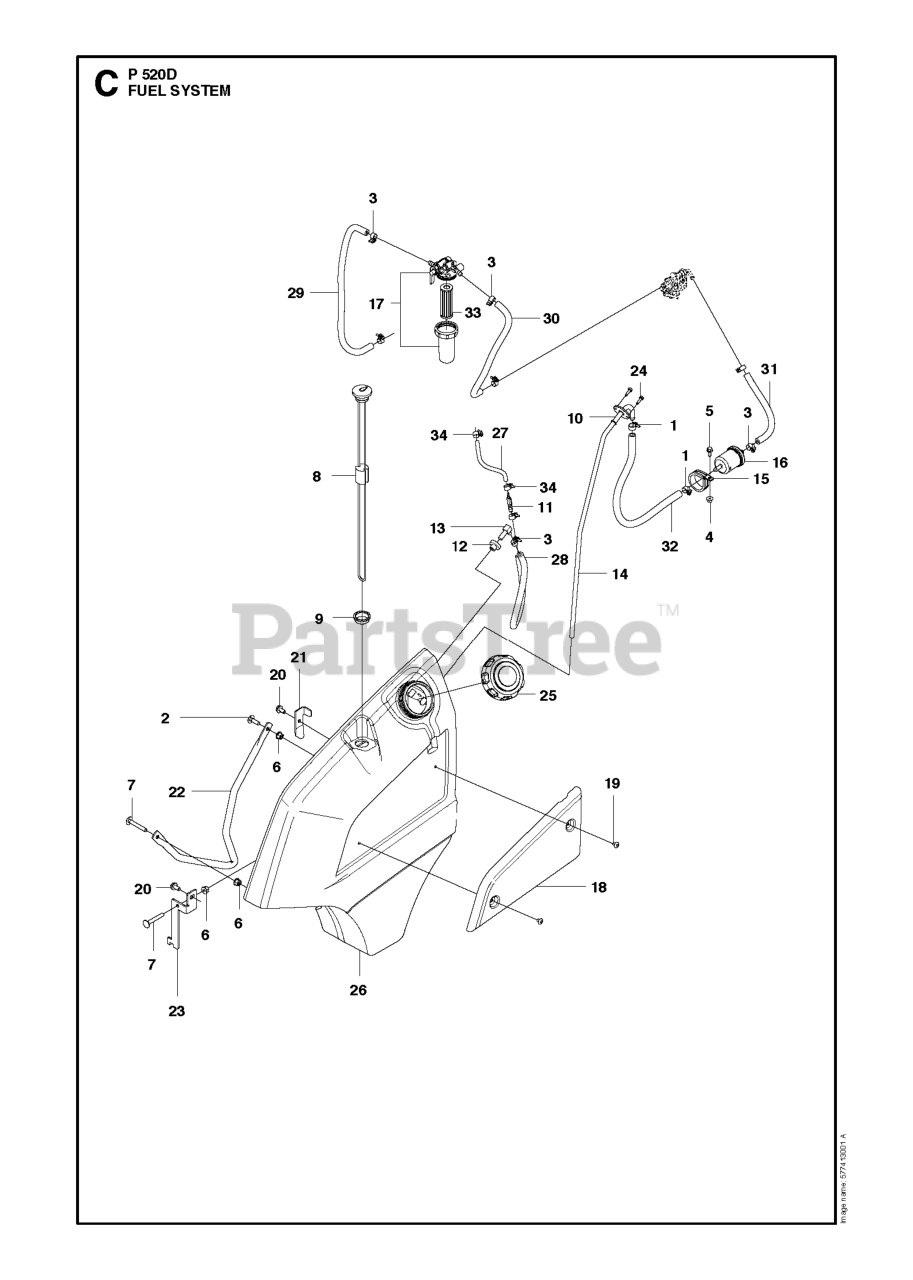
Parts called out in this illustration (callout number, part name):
1	HOSE CLAMP FUEL HOSE
3	RP HOSE CLAMP FUEL HOSE
4	NUT FLANGE
5	SCREW
6	NUT FLANGE
12	RUBBER GROMMET
15	HOSE CLAMP
25	TANK CAP - DIESEL
34	HOSE CLAMP FUEL HOSE
